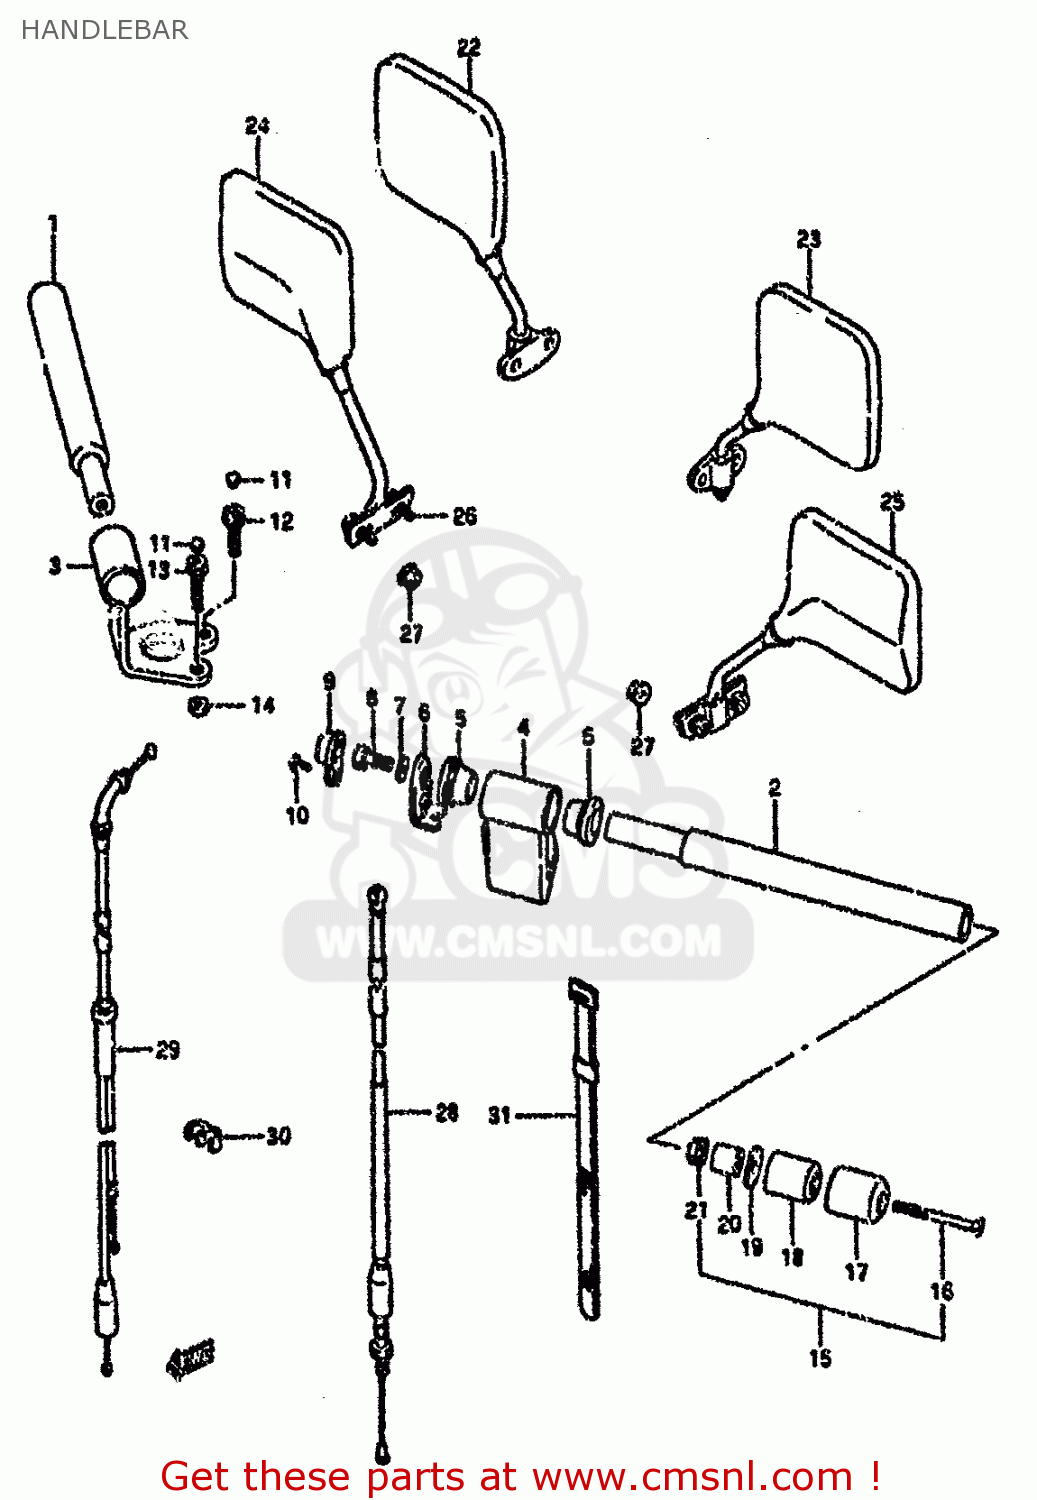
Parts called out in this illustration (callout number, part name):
1	HANDLEBAR, RH
2	HANDLEBAR,L
3	HOLDER,HANDLEBAR,R
4	HOLDER, HANDLEBAR LH
5	CUSHION, HANDLEBAR
6	PLATE, HANDLEBAR
7	WASHER,LOCK,8.
8	BOLT
9	CAP,HANDLEBAR BOLT
10	SCREW 5X10
11	CAP(OD:10)
12	BOLT
13	BOLT
14	NUT
15	BALANCER SET,HANDLEBAR
16	SCREW 6X65
17	CAP,BALANCER
18	BALANCER,HANDLE
19	SPACER,BALANCER
20	EXPANDER,HANDLE BALANCER
21	NUT
22	MIRROR ASSY,RR VIEW,R
23	MIRROR ASSY,RR VIEW,L
24	MIRROR ASSY,RR VIEW,R
25	MIRROR ASSY,RR VIEW,L
26	BOLT
27	NUT 6MM
28	CABLE ASSY,CLUTCH
29	CABLE ASSY,THROTTLE
30	CLIP
31	CLAMP(L:120)
